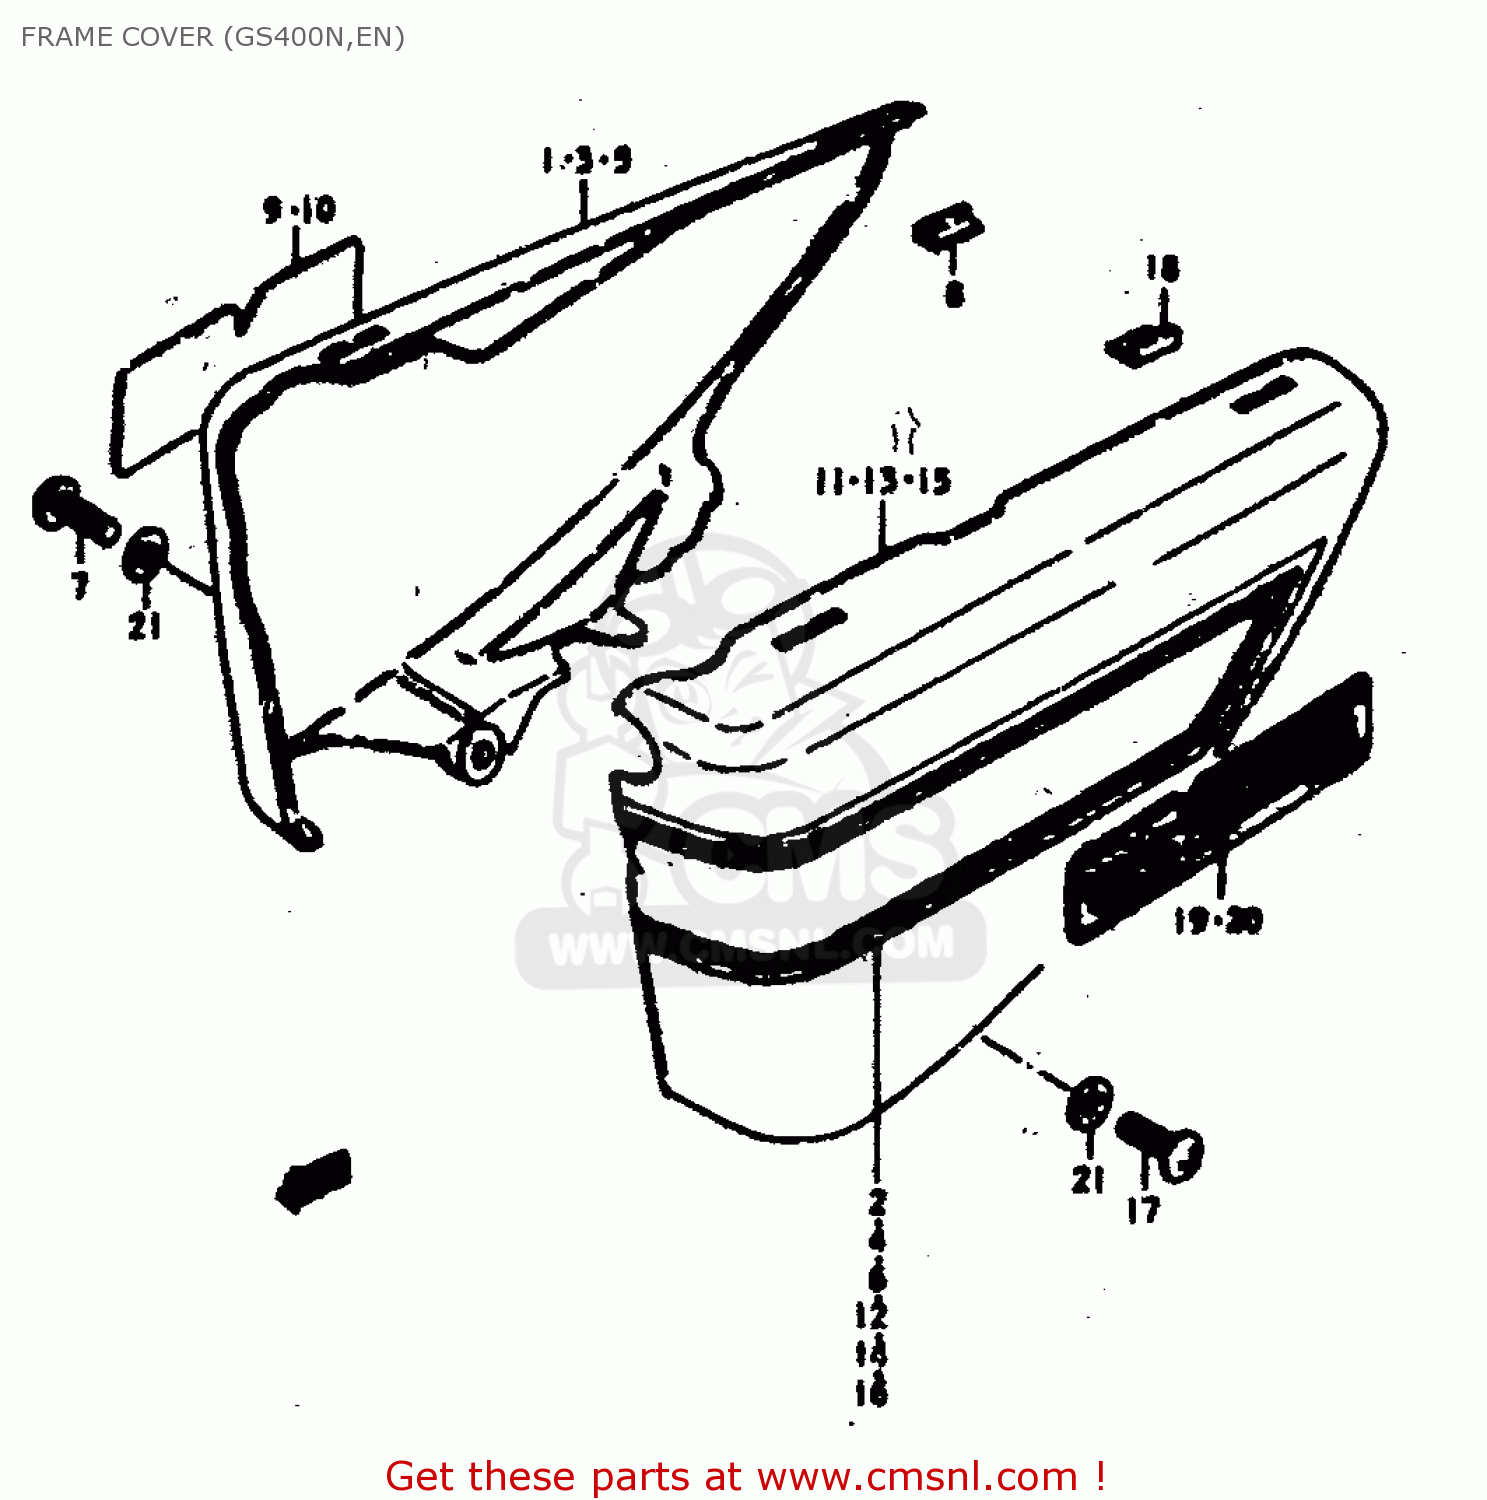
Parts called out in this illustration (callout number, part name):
1	COVER,FRAME,R(BLACK)
2	TAPE, RH
3	COVER, FRAME RH
4	TAPE, RH
5	COVER, FRAME RH
6	TAPE, RH
7	SCREW (6X15)
8	CUSHION,FRAME COVER
10	EMBLEM
11	COVER,FRAME,LEFT
12	TAPE, LH
13	COVER, FRAME LH
14	TAPE,LH
15	COVER, FRAME LH
16	TAPE, LH
17	SCREW
18	CUSHION,FRAME COVER
20	EMBLEM
21	WASHER (6.5X18X1.6)
